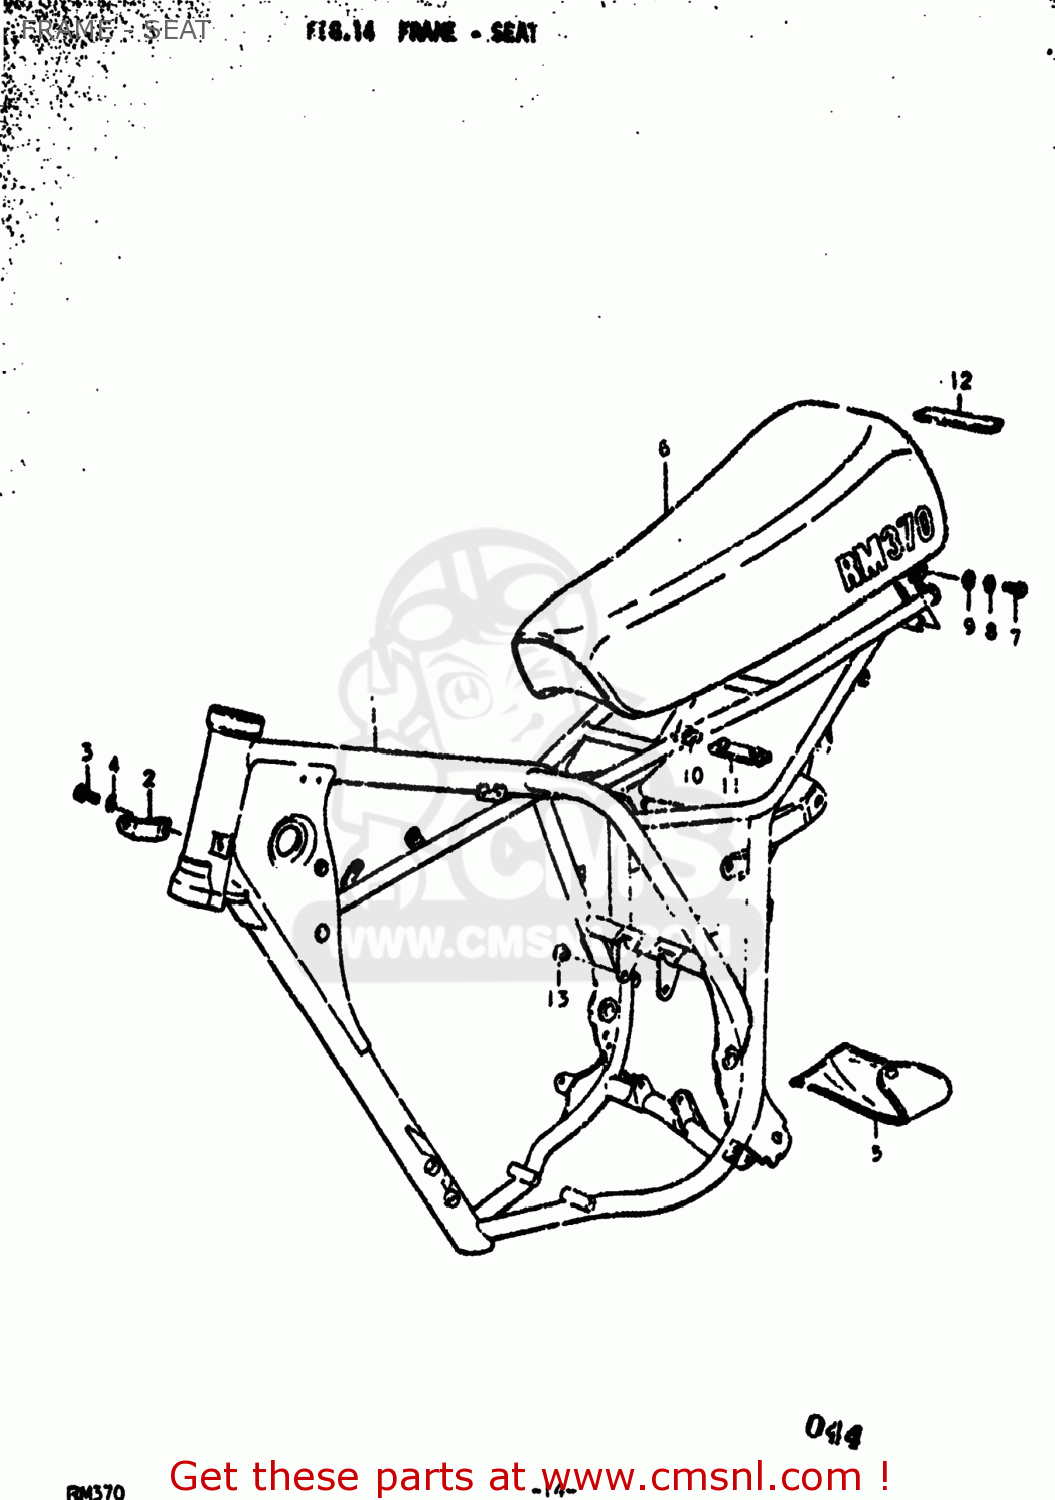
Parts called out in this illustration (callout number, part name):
1	FRAME
2	PLATE,ENGINE MOUNTING
3	BOLT
4	LOCK WASHER
6	SEAT ASSEMBLY
7	BOLT
8	LOCK WASHER
9	WASHER
10	CUSHION
11	CUSHION
12	CUSHION,FRAME
13	PLATE,FRAME BODY
